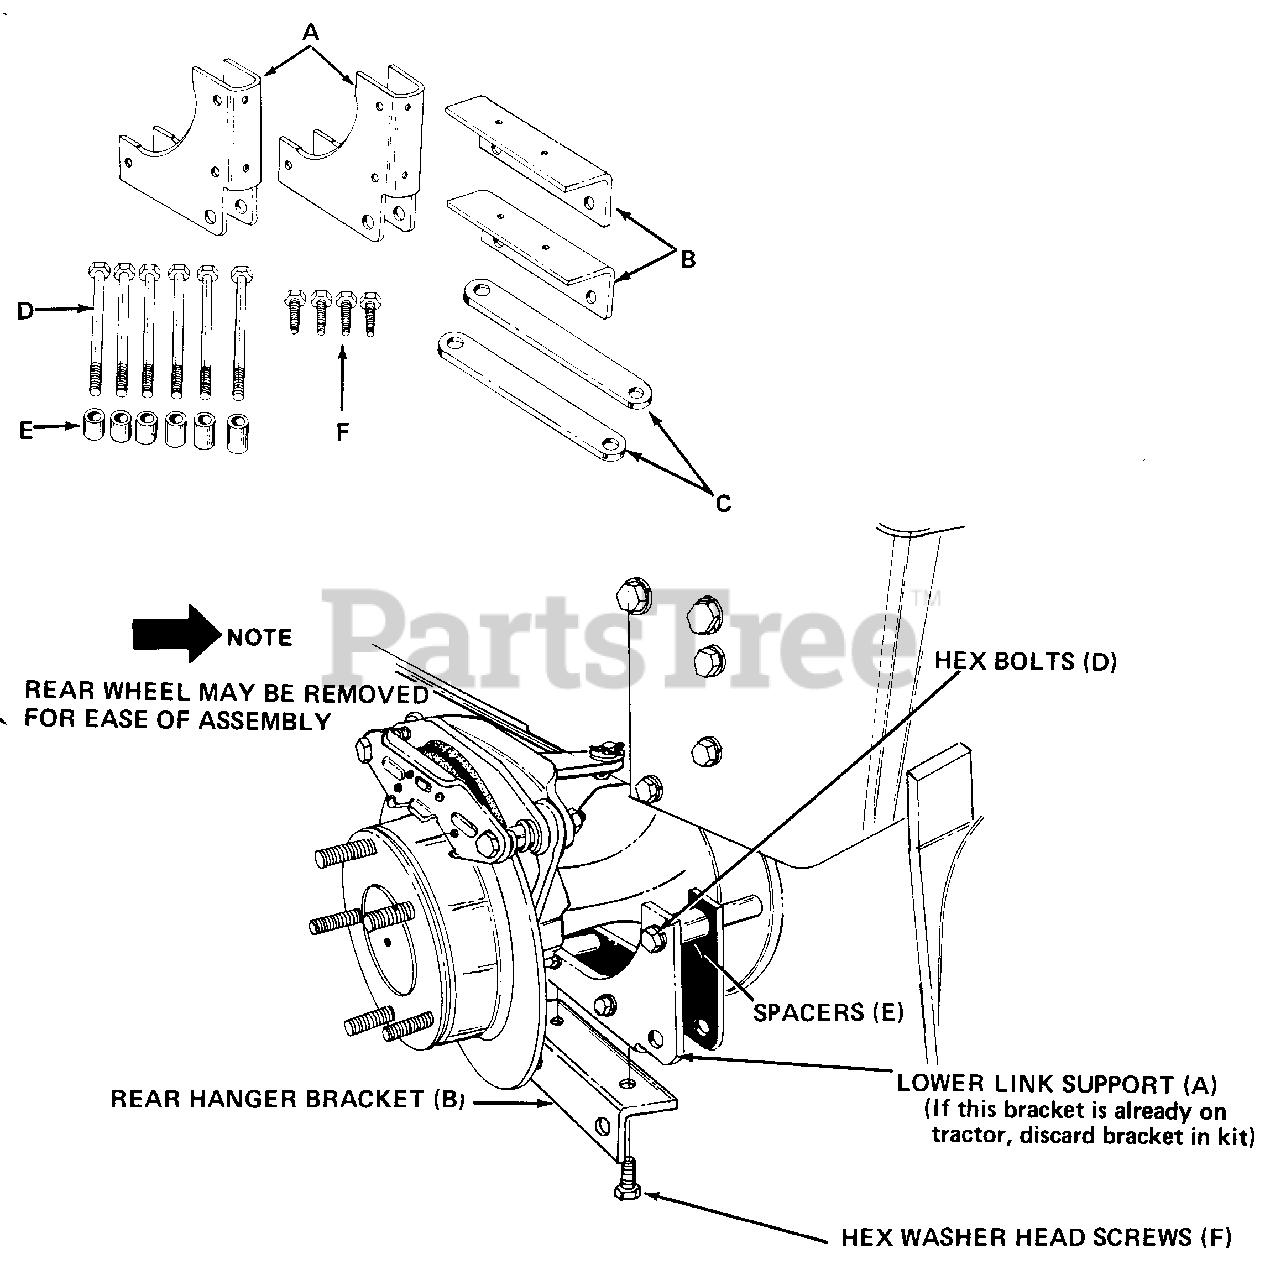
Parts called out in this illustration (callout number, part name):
A	2 Lower Link Support Plates
B	2 Rear Hanqer Brkt.
C	2 Lift Bracket 8.75" Lg.
D	6 Hex Bolt 3/8-16 x 4" Lg.
E	6 Support Spacers
F	4 Hex Wash. Hd. Self Tap Scr. 5/16-24 x.75" Lg.
